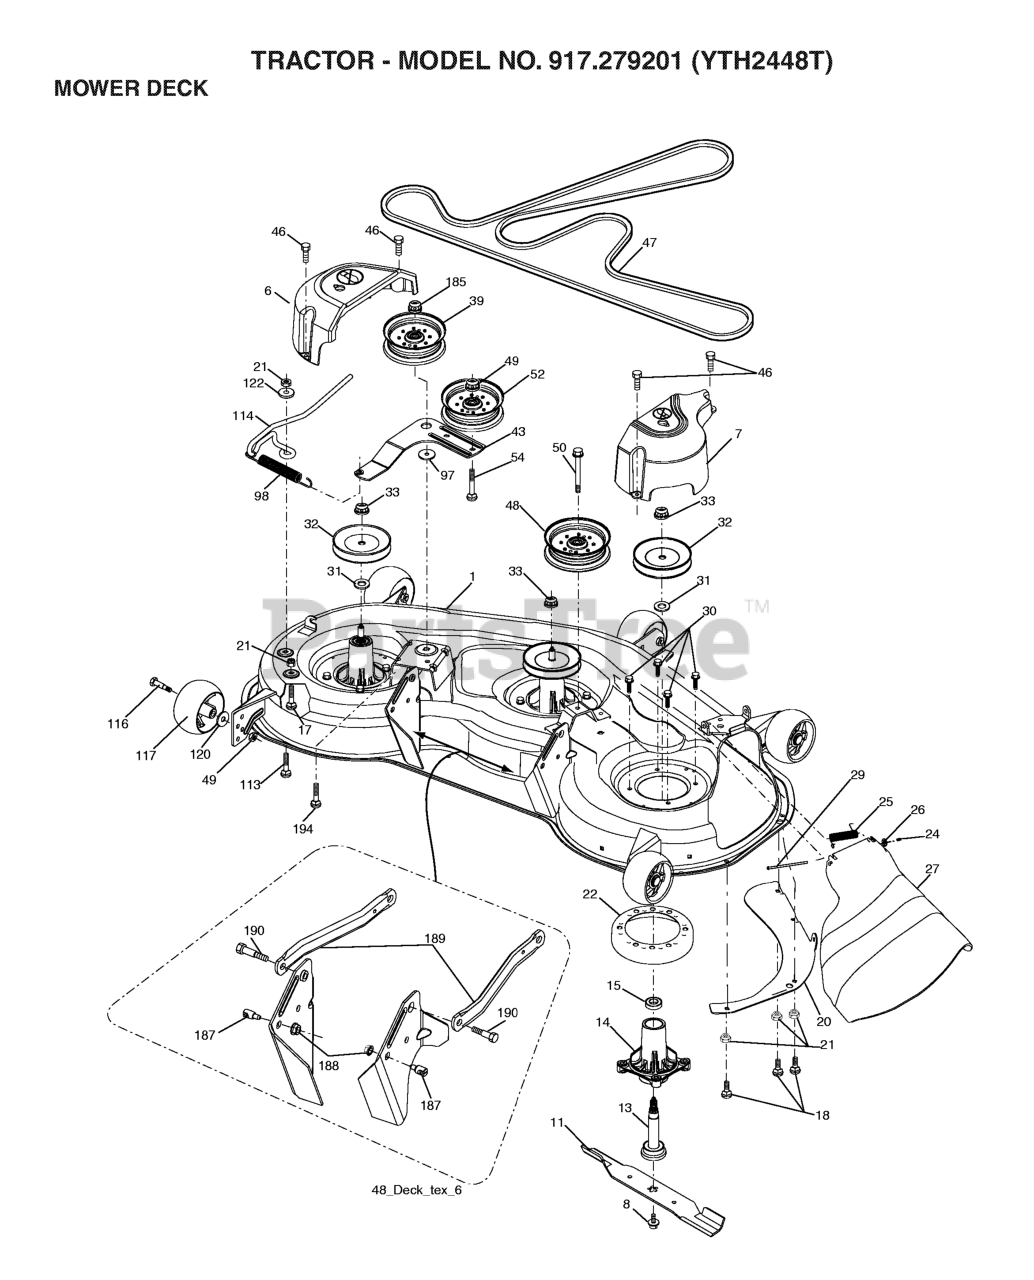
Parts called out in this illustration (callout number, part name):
1	DECK.WELDMENT.48"2006
6	COVER.MANDREL.LH.48"(2 2)
7	COVER.MANDREL.RH.48"
8	BOLT 7/16 ASM BLADE
11	48" HI-LIFT BLADE
13	SHAFT ASM MANDREL
14	RP.HOUSING.MANDREL.4PT.
18	BOLT
20	BAFFLE, VORTEX MWR
21	LOCKNUT
22	STRIPPER.MANDREL.ROUND.BLACK
24	CAP-SLEEVE LT
25	SPRING, TORSION
26	NUT PUSH M
27	DEFLECTOR SUBS TO 532 180655
29	ROD.HINGE
30	SCREW, WASHER HEAD
31	WASHER.SPACER.MANDREL
32	MANDREL.PULLEY.38.BRIGHT.ZINC
33	NUT.FLANGE.LOCK.TOP
39	PULLEY.IDLER.MWR.STATI.LH
46	SCREW.1/4-20X5/8
47	BELT.DRIVE.DECK
48	PULLEY.IDLER.2006
49	NUT LOCK FLG 3/8-16 UNC
50	SCREW TT 3/8-16X2-1/4 UNC
52	PULLEY.IDLER.FLAT
54	BOLT.3/8-16X1.50
98	SPRING, DECK DRIVE
114	ROD.TENSION.RELIEF.TEX (2 2)
116	BOLT.SHOULDER.3/8-16X3-5/8.
117	RP WHEEL. GUAGE RALLY
120	WASHER
122	BUSHING.RELIEF.TENSION
185	NUT.LOCK.FLANGE.7/16
187	STUD.FASTNER.W/ANTI-ROTATE
188	NUT LOCK HEX FLANGE 5/16-18
189	ARM.SUSPENSION.MOWER
190	BOLT.SHOULDER
194	BOLT.CARR.SQNK.7/16
